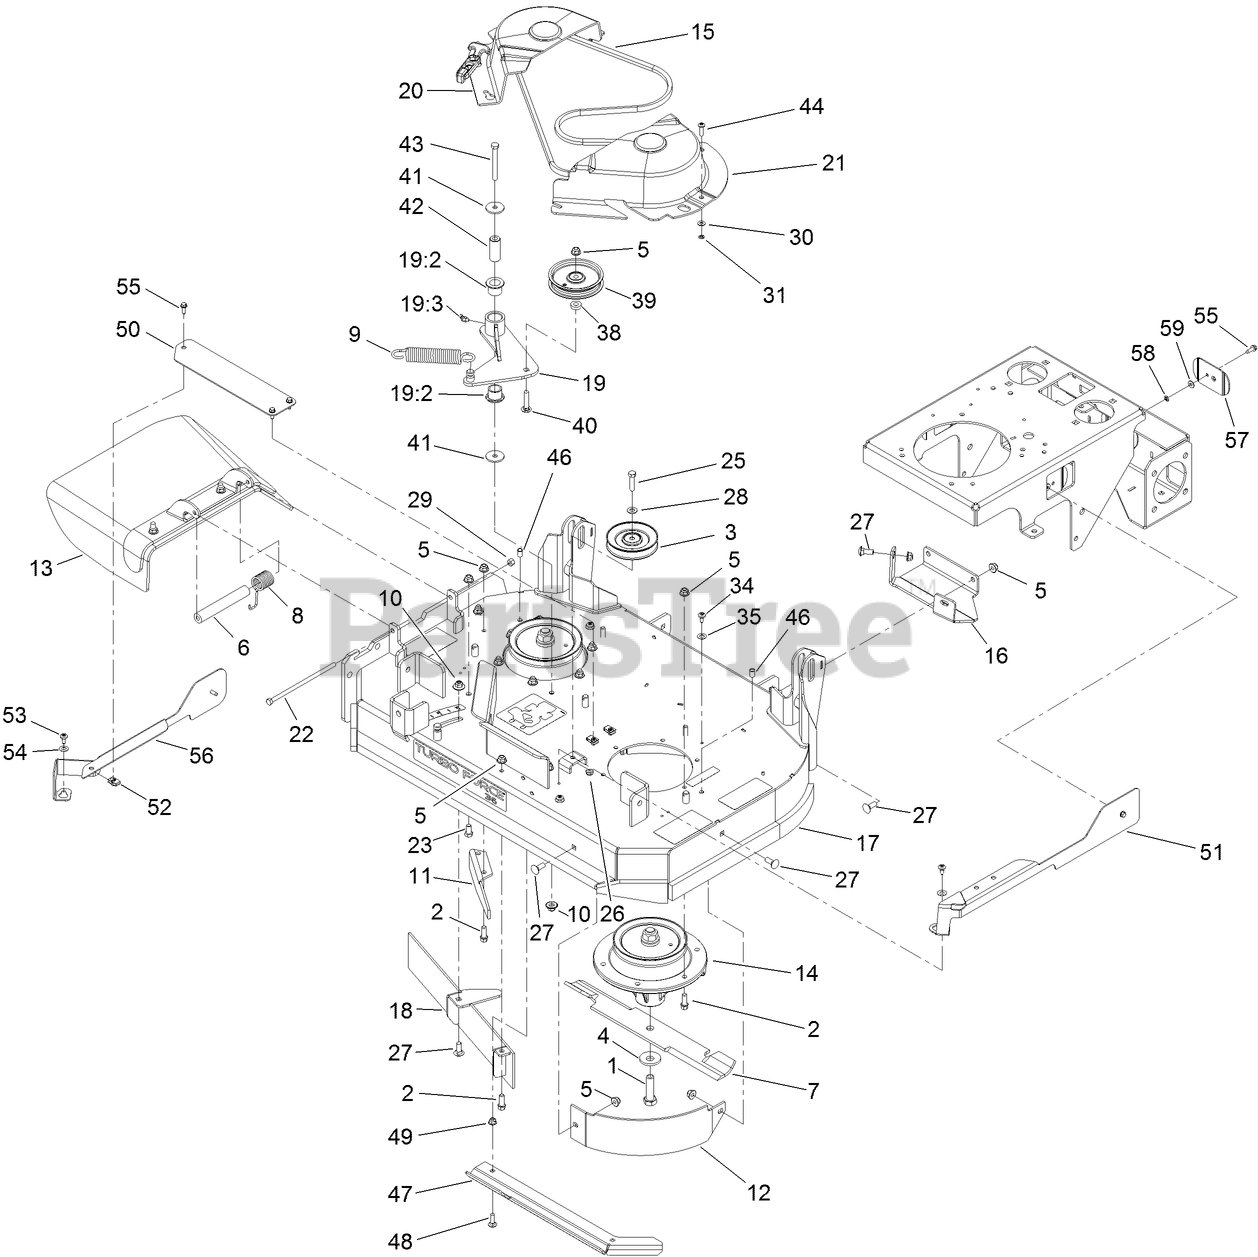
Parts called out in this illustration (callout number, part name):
1	SCREW-BLADE
3	PULLEY-IDLER
4	WASHER-BLADE BOLT, HEAVY
5	NUT-HF, NI
6	SPACER
7	BLADE-18IN, HI FLOW
8	SPRING-TORSION
9	SPRING-EXTENSION
10	NUT-FLANGE, NI
11	BAFFLE-DISCHARGE
12	BAFFLE-FRONT, LH
13	DEFLECTOR ASM
14	SPINDLE ASM
15	BELT-V
16	PLATE-SKID
17	DECK AND DECAL ASM
18	FRONT BAFFLE ASM
19	IDLER ARM ASM
19:2	BUSHING
19:3	FITTING-LUBE, 45 DEG
20	COVER-BELT, RH
21	COVER-BELT, LH
22	SCREW-HH
23	SCREW-HH
25	SCREW-HH
27	SCREW-HH
28	WASHER-FLAT
29	NUT-LOCK, NI
30	WASHER-FLAT
31	NUT-RETAINER
34	SCREW-SHOULDER
35	WASHER-THRUST
38	SPACER
39	PULLEY-IDLER
40	SCREW-HH
41	WASHER
42	SPACER-PLAIN
43	SCREW-HH
44	SCREW-TTH
46	NUT-CLINCH
47	EXTENDER-DECK
48	BOLT-CARR
49	NUT-HF, NI
50	GUARD-DECK, CENTER
51	GUARD-DECK, LH
53	SCREW-SHOULDER
54	WASHER-THRUST
55	SCREW-HWH, THREAD ROLL
56	GUARD-DECK, RH
57	GUARD-PLATE
58	NUT-RETAINER
59	WASHER
